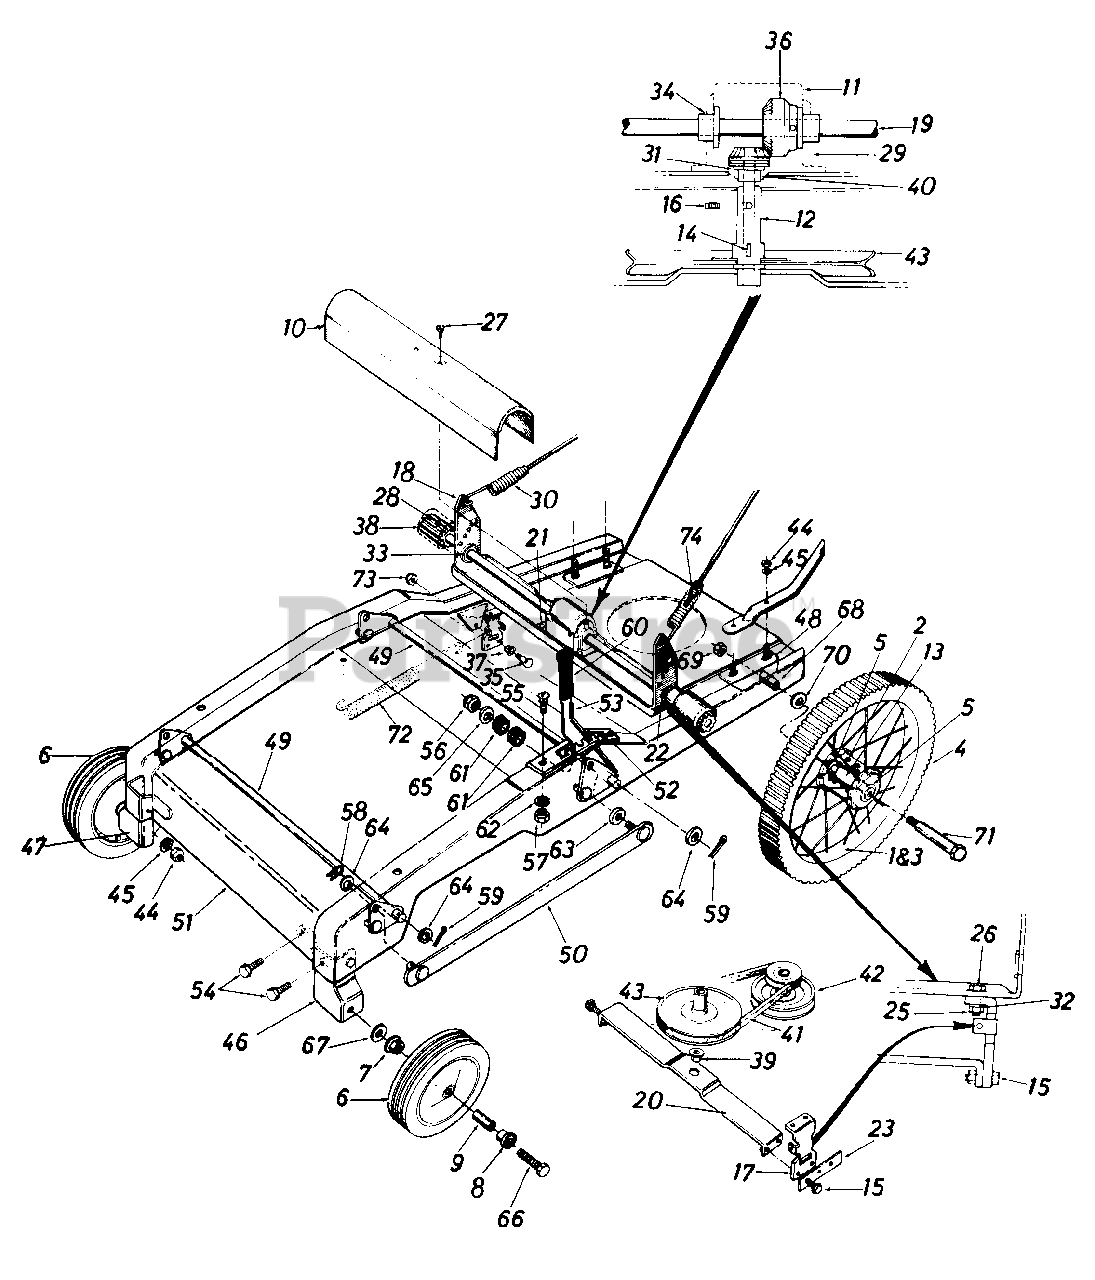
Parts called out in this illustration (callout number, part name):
1	16" Wheel Ass'y. Comp. - Rear
3	Rear Wheel - Rim Only
4	Rear Wheel - Tire Only 16 x 1.75
5	Ball Brg. .630" I.D.
6	Wheel Ass'y. Comp. - Front - 8 x 1.75
7	Flanged Ball Brg. 3/8" I.D.
8	Flanged Ball Brg. 1/2" I.D.
9	Spacer 3/8" I.D.
10	Top Drive Frame Cover
11	Gear Box Cover
12	Pinion Ass'y.
13	Wheel Spacer
14	#2 Woodruff Key 3/32 x 1/2" Dia. Hdn.
15	Hex Sems Bolt 5/16-18 x 1.00" Lg.
16	Set Scr. 5/16-18 x .25" Cup
17	Bottom Drive Frame
18	Top Drive Frame Ass'y.
19	Drive Shaft
20	Bottom Drive Frame Ass'y.
21	Hex Self-Tap Scr. 1/4-20 x .62" Lg.
22	Collar 5/8" I.D.
23	Drive Frame Stop
25	Hex Nut 5/16-18 Thd.
26	Hex Sems Bolt 5/16-18 x .75" Lg.
27	Hex Wash. Hd. AB-Tap Scr. #8 x .50" Lg.
28	Spring Pin Spir. 3/16" Dia. x 1.00" Lg.
29	Gear Box
30	Extension Spring
32	L-Wash. 5/16" I.D.
33	Ball Brg. .630" I.D.
34	Flange Brg. .630" I.D.
35	Shld. Bolt .443 Dia. x .330
36	Bevel Gear .62" I.D. 28 Teeth
37	Pivot Slide
38	Drive Pinion
39	Hex Flange Brg. .503" I.D.
40	Flange Brg. .503" I.D. w/Groove
41	3V-Belt 28" Lg.
42	Double Pulley
43	3/8" V-Pulley .502" I.D. x 6.5" O.D.
44	Hex Nut 3/8-16 Thd.
45	L-Wash. 3/8" I.D.
46	Wheel Brk't. Ass'y. - L.H.
47	Wheel Brk't. Ass'y. - R.H.
48	Rear Wheel Brk't. Ass'y.
49	Lift Bracket Shaft Ass'y.
50	Connecting Link Ass'y.
51	Frame
52	Lift Handle Support Brk't.
53	Lift Handle
54	Hex Sems Bolt 5/16-18 x .75" Lg.
55	Carriage Bolt 5/16-18 x .62" Lg.
56	Hex Ins. L-Nut 3/8-24 Thd.
57	Hex Nut 5/16-18 Thd.
58	Intern. Cot. Pin 5/16" Dia.
59	Cot. Pin 1/8" Dia. x 1.00" Lg.
60	Grip - Black
61	Rubber Wash. .33" I.D. x .87" O.D.
62	L-Wash. 5/16" I.D.
63	Fl-Wash. .406" I.D. x 1.25" O.D. x .164
64	Fl-Wash. .510" I.D. x 1.0" O.D. x .060
65	Fl-Wash. .385" I.D. x .87" O.D. x .06
66	Hex Bolt 3/8-16 x 2.00" Lg.
67	Bell-Wash. .400" I.D. x .88" O.D.
68	Spacer .523" I.D. x .640" O.D. x 1.955
69	Hex Top L-Nut 3/8-16 Thd.
70	Fl-Wash. .531" I.D. x .93" O.D.
71	Shld. Bolt .498" Dia. x 4.755
72	Extension Spring .56" O.D. x 8.25" Lg.
73	Hex Ins. L-Nut 5/16-18 Thd.
74	Hex Ins. L-Nut 1/4-20 Thd.
